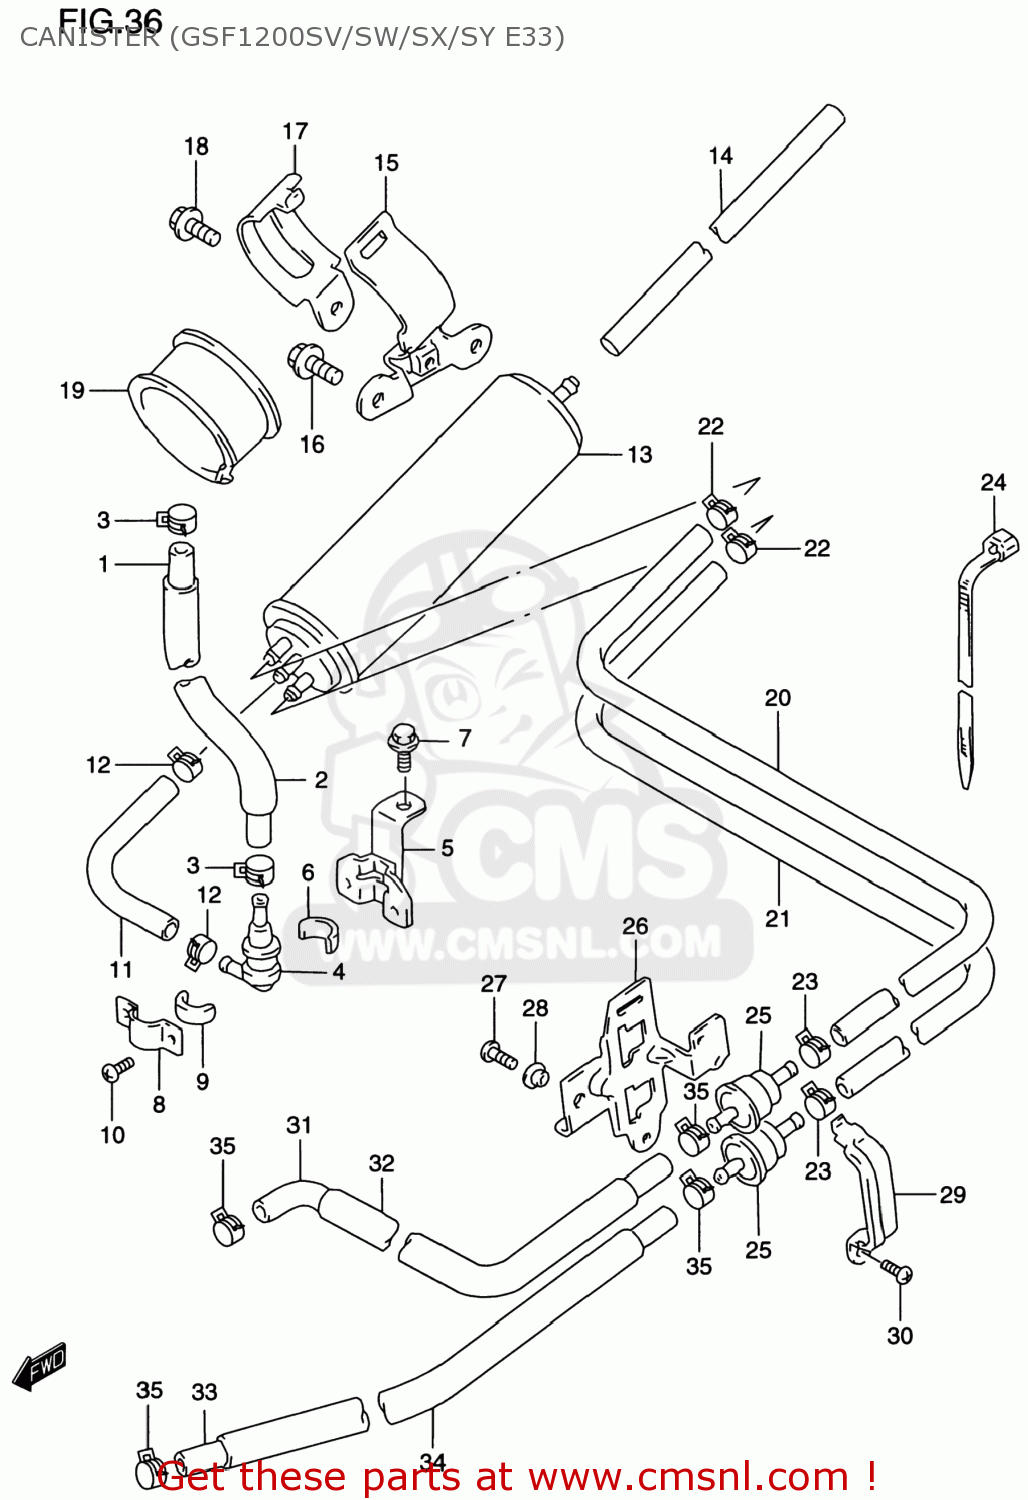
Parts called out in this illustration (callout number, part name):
1	HOSE(5.4X11.4X600)
2	PROTECTOR(14.5X15.5X600)
3	CLIP
4	VALVE,FUEL TANK BREATHER
5	BRACKET COMP,FUEL TANK
6	CUSHION
7	BOLT
8	PLATE,FUEL TANK BREATHER NO.2
9	CUSHION
10	SCREW
11	HOSE(5.4X11.4X600)
12	CLIP
13	CANISTER ASSY,CHARCOAL
14	HOSE(7X12X600)
15	BRACKET,CANISTER
16	BOLT
17	HOLDER,CANISTER
18	SCREW 6X12
19	CUSHION,CANISTER
20	HOSE(5.4X11.4X600)
21	HOSE(5.4X11.4X600)
22	CLIP
23	CLIP
24	CLAMP(L:125)
25	VALVE,CANISTER PURGE
26	BRACKET,CANISTER PURGE VALVE
27	SCREW 5X12
28	WASHER (5X14X1)
29	HOLDER,CANISTER PURGE
30	SCREW
31	HOSE(5.4X11.4X600)
32	PROTECTOR(14.5X15.5X600)
33	HOSE(5.4X11.4X600)
34	PROTECTOR(14.5X15.5X600)
35	CLIP
